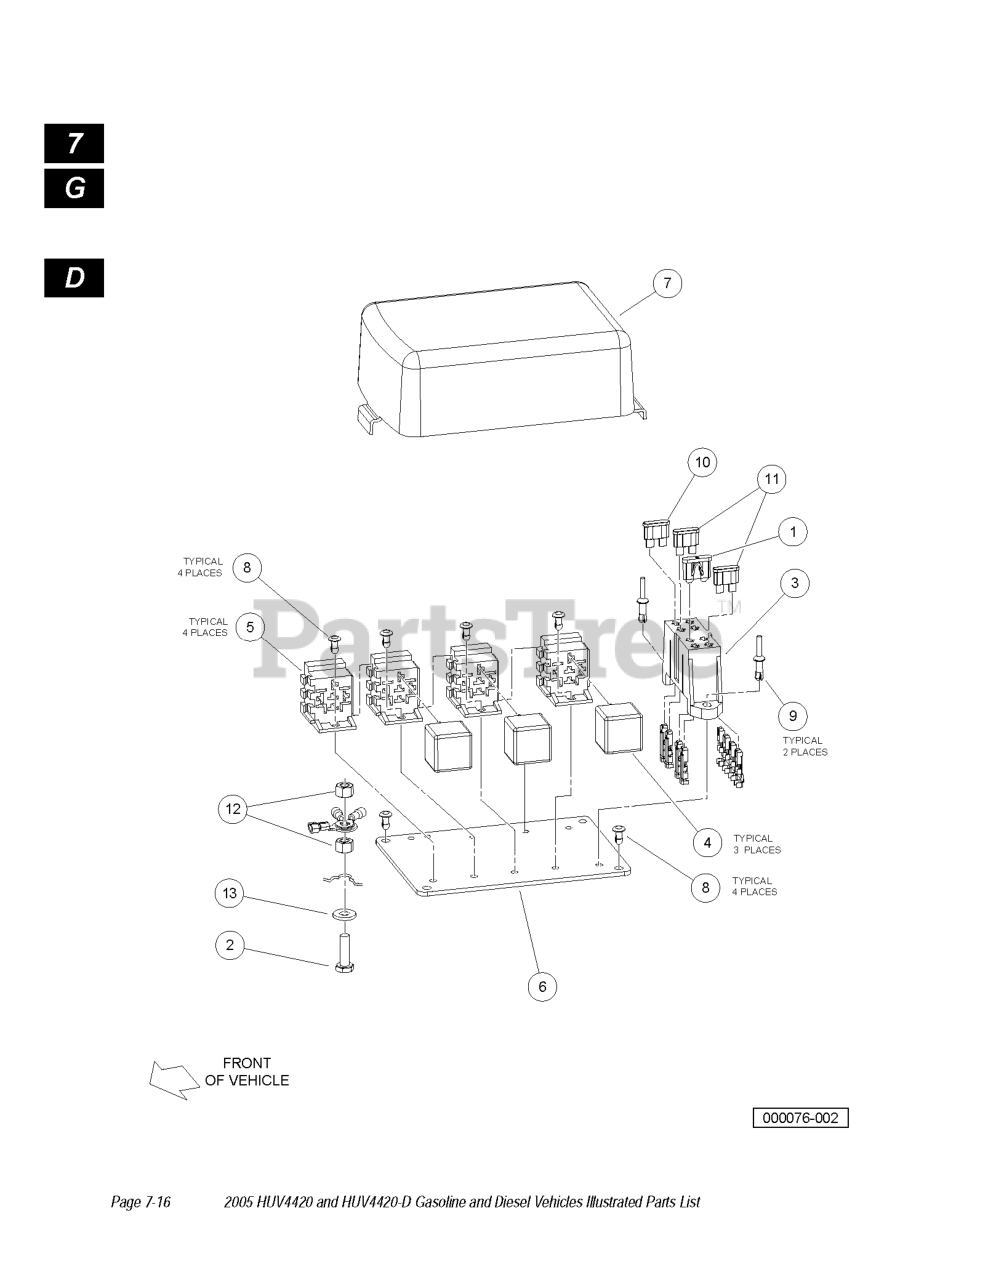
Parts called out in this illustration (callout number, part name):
1	10 AMP FUSE
3	FUSE BLOCK
4	RELAY, MINI ISO, SPDT
6	PLATE, ELECTRICAL
7	COVER, ELECTRICAL
8	FASTENER, PUSH-IN
9	RIVET, DRIVE
10	FUSE, ATC/ATO, 25A
11	FUSE, ATC/ATO, 30A
12	LOCKNUT, 1/4-20 DIMPLED
13	WASHER 1/4 FLAT
